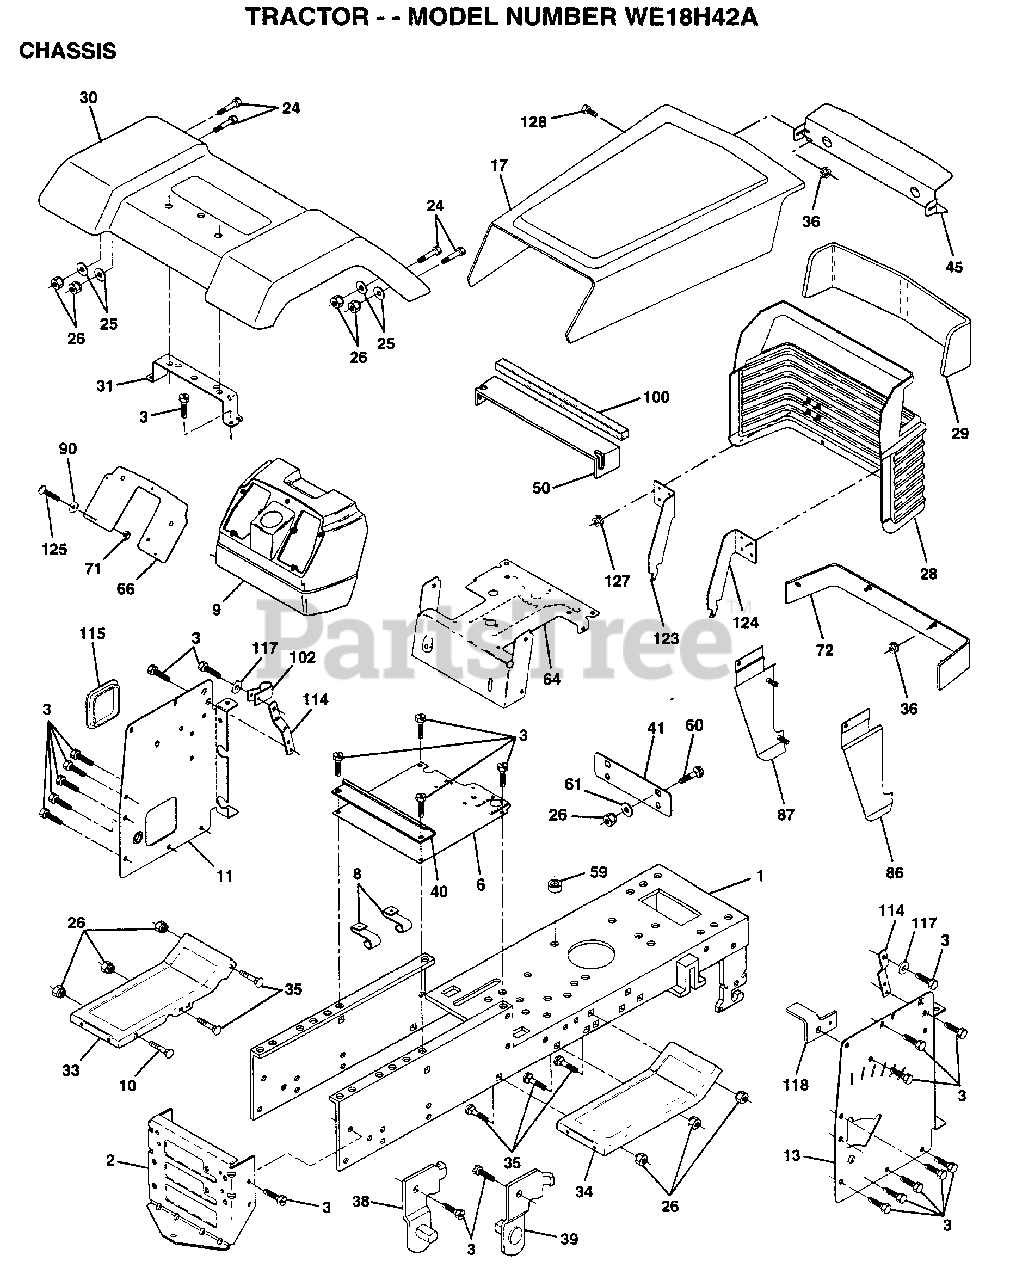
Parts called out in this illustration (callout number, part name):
1	CHASSIS.WLD.11GA
3	SCREW
8	"CLIP,INSULATOR"
9	DASH.PLASTIC.BLK
11	PANEL.DASH.LH.
13	PANEL.DASH.RH.NOT
17	HOOD/GRILLE ASM
24	BOLT
25	WASHER
26	NUT
28	GRILLE ASM WELD
31	BRACKET SUPT FEND
33	FOOTREST.LH.LT/GT
34	FOOTREST.RH.LT/GT
35	BOLT
36	PAL NUT LT
38	BRACKET ASM LH
39	BRACKET ASM RH
40	SPACER FENDER LT
41	PLATE EXTEN FEND
50	"BAFFLE,HOOD"
60	BOLT
61	WASHER
66	PLATE DASH SILKSC
71	NUT HXKEP 1/4X20
72	STRAP FENDER ASM
86	PANEL SIDE RH ASM
87	PANEL SIDE LH ASM
90	WASHER PM
100	FOAM STRIP T
102	"CLIP,INSULATOR"
114	BRACKET.SUPT.DASH
115	COVER ACCESS
117	WASHER.SERRATED.
118	BRACKET.CLUTCH.MC
123	BRACKET.PICK.RH.
124	BRACKET.PICK.LH.
125	SCREW
127	PAL NUT
128	SCREW SPECIAL
